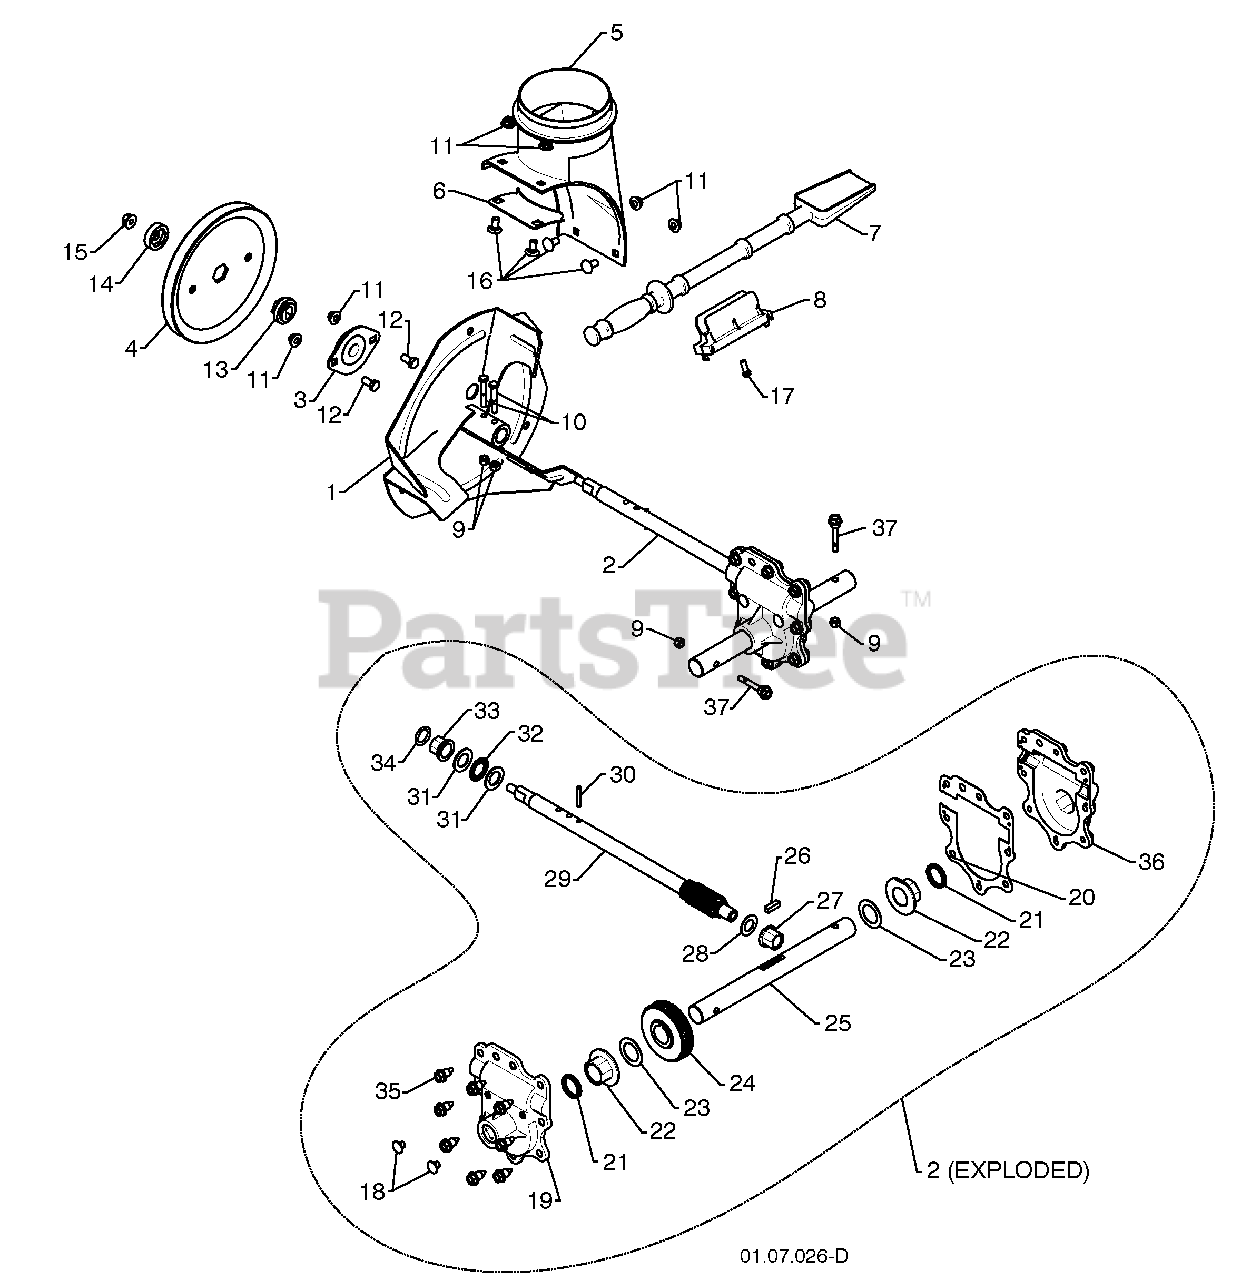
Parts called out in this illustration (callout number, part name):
2	GEARBOX ASSEMBLY
4	IMPELLER PULLEY
5	DISCHARGE BASE
6	CORNER BRACKET
7	CLEAN OUT TOOL
9	NUT 1/4-20
10	SCREW 1/4-20 X .625
11	NUT 5/16-18
12	SCREW 5/16-18 X .625
13	IMPELLER HUB
14	IMPELLER SLEEVE
15	NUT 3/8-16
16	CARRIAGE BOLT
17	SCREW 13-16 X .625
18	PLUG
19	GEARBOX COVER RH
21	SEAL
22	BEARING
23	THRUST WASHER 1.00
24	WORM GEAR
25	AUGER SHAFT
26	SQUARE KEY
27	BEARING
28	THRUST WASHER
29	IMPELLER SHAFT
30	ROLL PIN
31	THRUST WASHER
32	THRUST BEARING
35	SCREW 5/16-18 X .750
36	GEARBOX COVER LH
37	SHEAR BOLT
